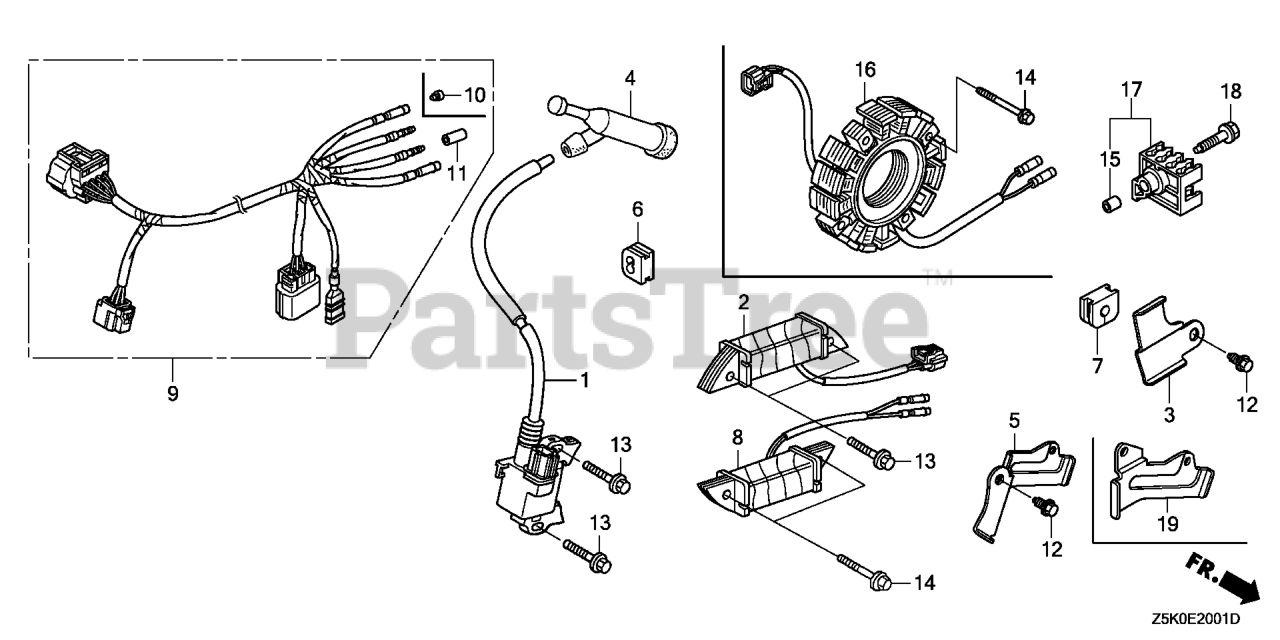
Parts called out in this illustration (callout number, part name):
1	COIL ASSY., IGNITION
2	COIL ASSY., POWER
3	BRACKET B, HARNESS
4	CAP ASSY., NOISE SUPPRESSOR (NGK Y-EZD)
5	CLAMP, WIRE
6	GROMMET, WIRE
7	GROMMET, WIRE
8	COIL ASSY., CHARGE (2.9A)
9	WIRE HARNESS ASSY., ENGINE (HM,SW)
10	PLUG, CONNECTOR (INNER) (TROLLING CONTROL)
11	PLUG, CONNECTOR (OUTER) (ENGINE NO.)
12	BOLT, FLANGE (6X12) (CT200)
13	BOLT, FLANGE (6X28) (CT200) Use up to Engine SN 1530314.
14	BOLT, FLANGE (6X32)
15	COLLAR B, AIR CLEANER
17	HOLDER, CONNECTOR
18	BOLT, FLANGE (6X20) (CT200)
